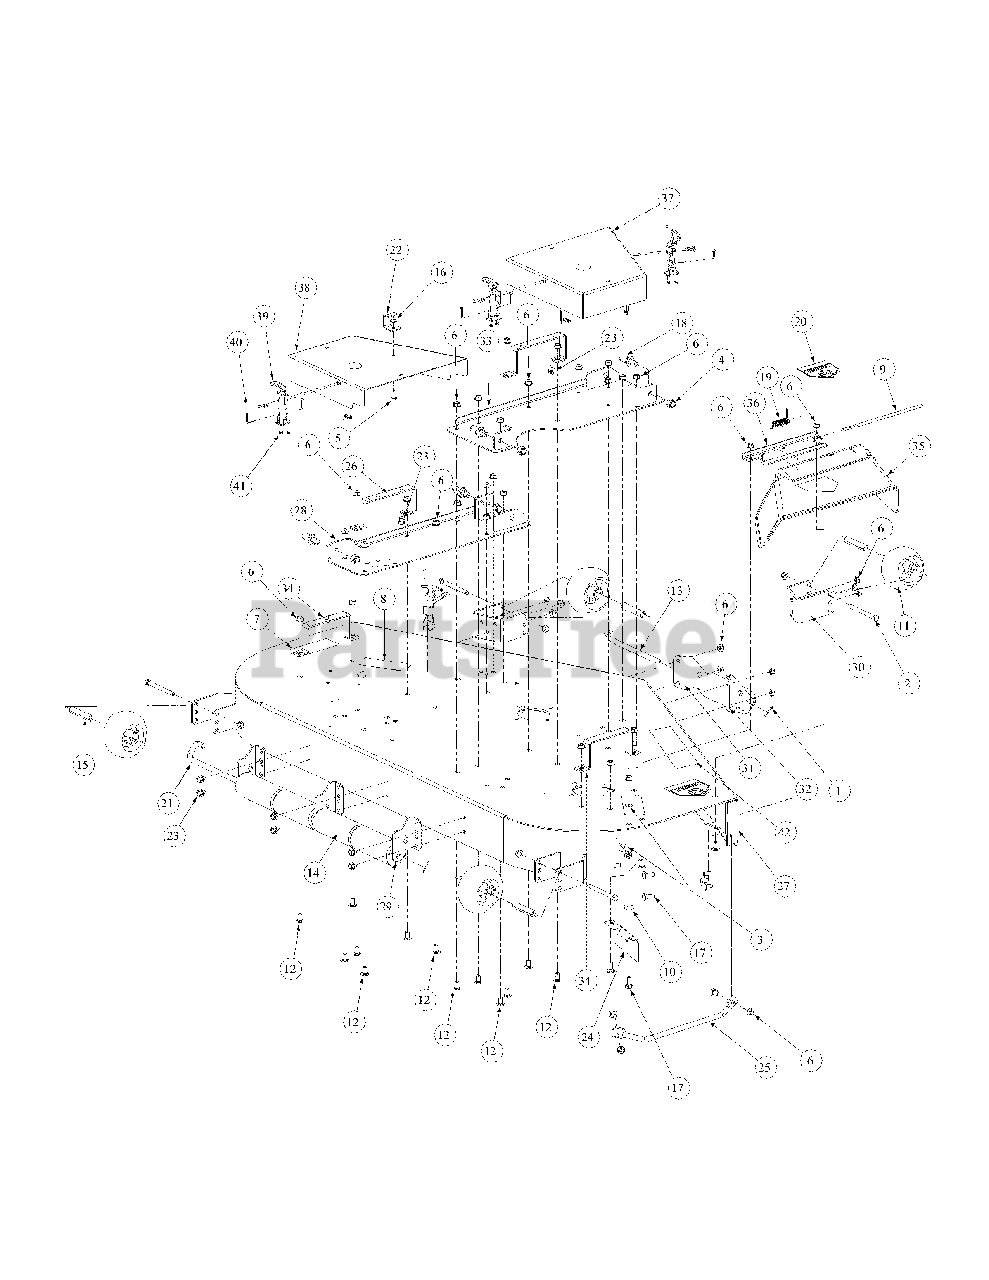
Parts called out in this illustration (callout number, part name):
1	Cotter Pin, .125 Dia. x 1.0
2	Hex Cap Screw, 3/8-16, 3.75
3	Flat Washer, 3/8
4	Lock Nut, Nylon Insert, 1/2-13
5	Hex Cap Screw, 5/16-18 x 3/4
6	Flange Lock Hex Nut, 3/8-16
7	Decal, Rotating Blade
8	Decal, Warning Shield Missing
9	Chute Deflector Rod
10	Idler Washer
11	Complete Wheel, 5.00 Dia.
12	Carriage Bolt, 3/8-16 x .75 Lg.
13	Roller Pin, 1/2 Dia. x 7.31 Lg.
14	Front Roller
15	Wheel Spacer
16	Hex Flange Lock Nut, 5/16-18
17	Carriage Bolt, 3/8-16 x 1
18	Pin, 5/8 Dia. x 1.2 Lg.
19	Torsion Spring, 0.4ID x 2.16Lg
20	Decal, Danger Hand and Feet
21	Roller Pin
22	Tension Rod Stop Bracket
23	Hex Index Washer Screw, 3/8-16, .5
24	Chute Bracket
25	Finger Guard
26	Belt Cover Support
27	60 Deck Assembly
28	Left Hand Mount Deck Bracket Assembly
29	Deck Roller Mount Bracket
30	Anti-Scalp Wheel Front Mount Bracket
33	Right Hand Deck Bracket Assembly
34	Outer Belt Cover Support Assembly
35	Chute Deflector
36	Chute Deflector Bracket
37	Right Hand Deck Belt Cover Weldment
38	Left Hand Deck Belt Cover Weldment
39	T-Handle Latch Draw
40	Phillips Head Screw, 10-32
41	Lock Nut, Nylon Insert, 10-32
42	Commercial Mower Label
